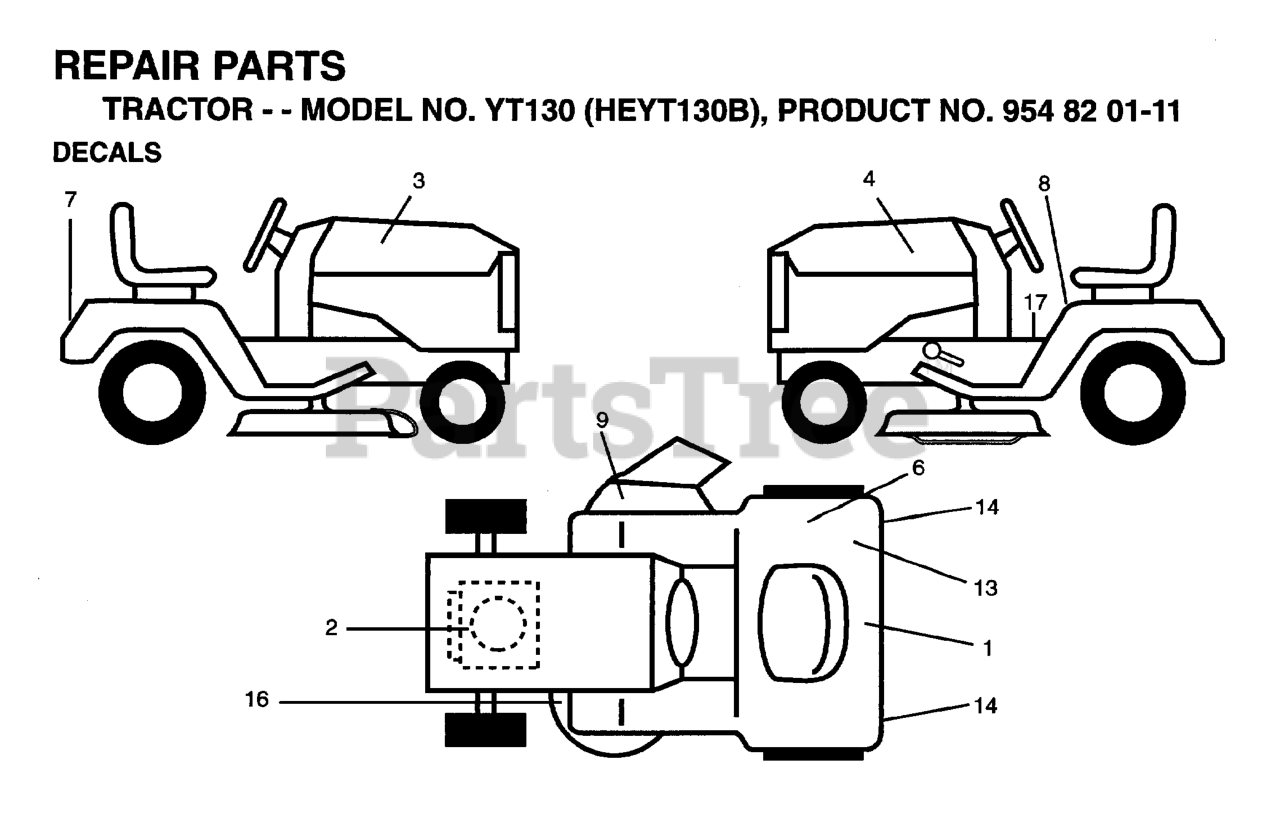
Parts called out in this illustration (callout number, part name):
1	DECAL, BATTERY DANGER
2	DECAL HP ENGINE
3	DECAL HD RH YT130
6	DECAL EUROPE STANDARD CE
7	DECAL FENDER HUSQ
8	DECAL READ OWNER'S MAN SYMS
9	DECAL MOWER CUT/FINGER
14	REFLECTOR-TAIL YT
16	DECAL V-BELT SCHEMATIC
17	DECAL PARK BRAKE
